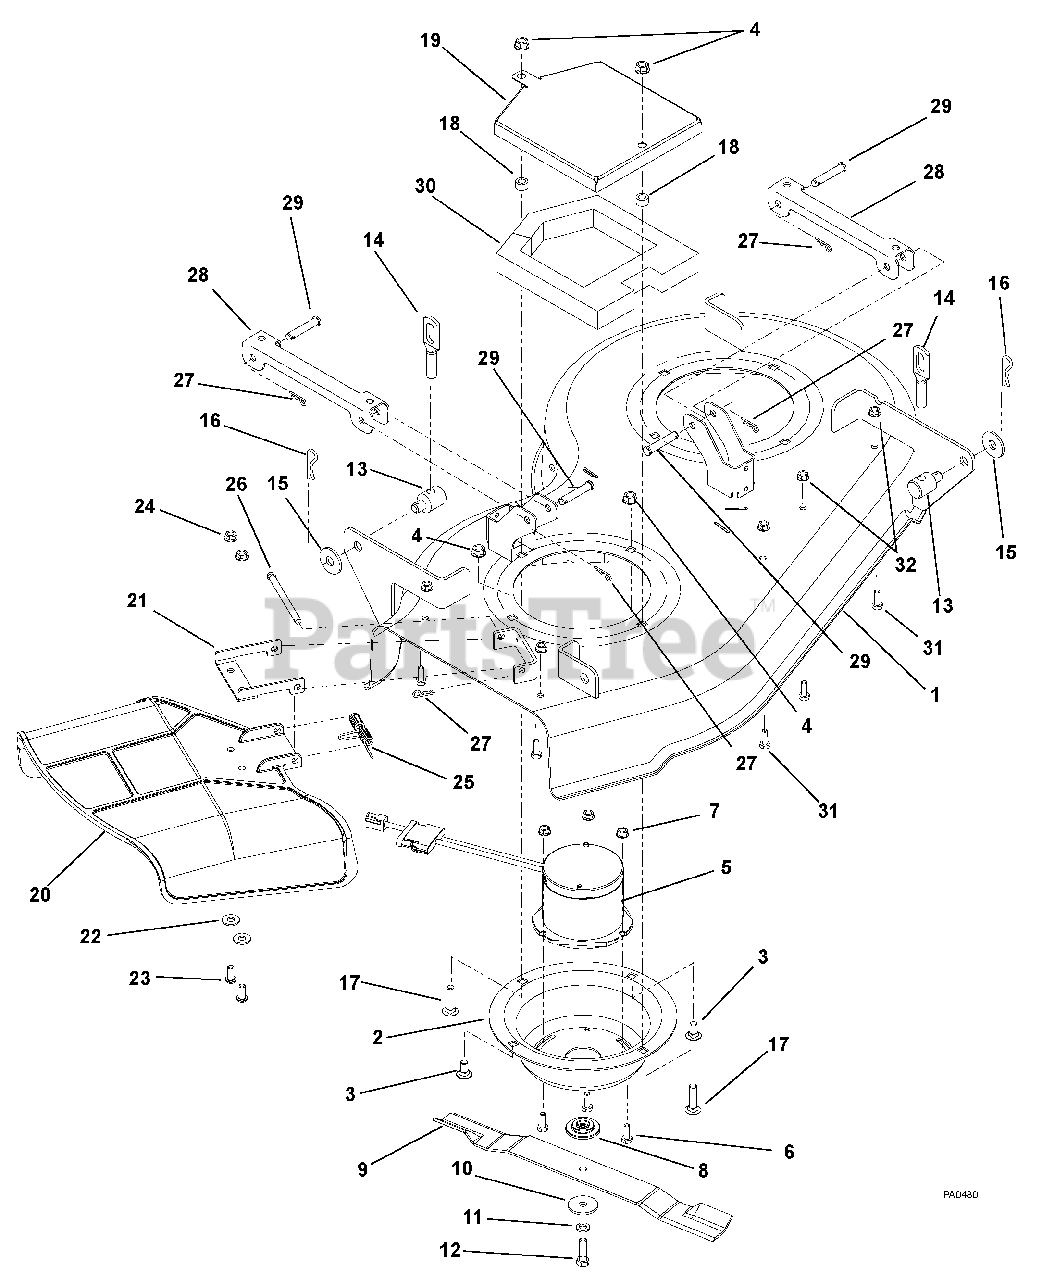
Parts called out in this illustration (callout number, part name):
1	34" STAMPED DECK ELECTRIC
2	SUMP,DECK -AMP
3	@BLT-RDHDSQNK .38-16X.75 G5YZ
4	@NUT-LK-TOP-FLG .38-16 YWZC
5	MOTOR, 1.7 HP ELEC. BRUSHLESS
6	@BLT-HEX .25-20X.75 GR5 YWZC
7	@NUT-LK-NYL-FLG .25-20 YWZC
8	ADAPTER, MOWER BLADE
9	BLADE, MOWER - 17.38
10	WSHR-FL-STL .390X1.5X.125 YWZC
11	@WSHR-LK .38X.094 REG YWZC
12	BLT-HEX .38-24X1.25 GR8 YWZC
13	TRUNNION-.50
14	DECK LINK
15	WSHR-FL-STL.511X1.441X.125 YWZ
16	PIN, HAIR, EXT - #16 YWZC
17	@BLT-RDHDSQNK .38-16X1.75 G5YZ
18	BSHG-SPCR .380X.625X.625
19	COVER, MOTOR
20	MOLDED CHUTE, ZOOM
21	CHUTE REINFORCEMENT
22	@WSHR-FL-STL.38X.875X.083 YWZC
23	SCR-SKH .31-18X.75 BTNHD YWZC
24	@NUT-LK-TOP-FLG .31-18 YWZC
25	SPRING, TORSION
26	PIN, 5/16 X 3.88"
27	PIN-HAIR INT .08X.18X1.18 YWZC
28	BRKT-STABILIZER LINK
29	PIN-CLEV .375 X 2.00 YWZC
30	FOAM, DECK MOTOR COVER
31	@BLT-HEX .31-18X.75 GR5 YWZC
32	@NUT-SPNLK-FLG .312-18 YWZC
